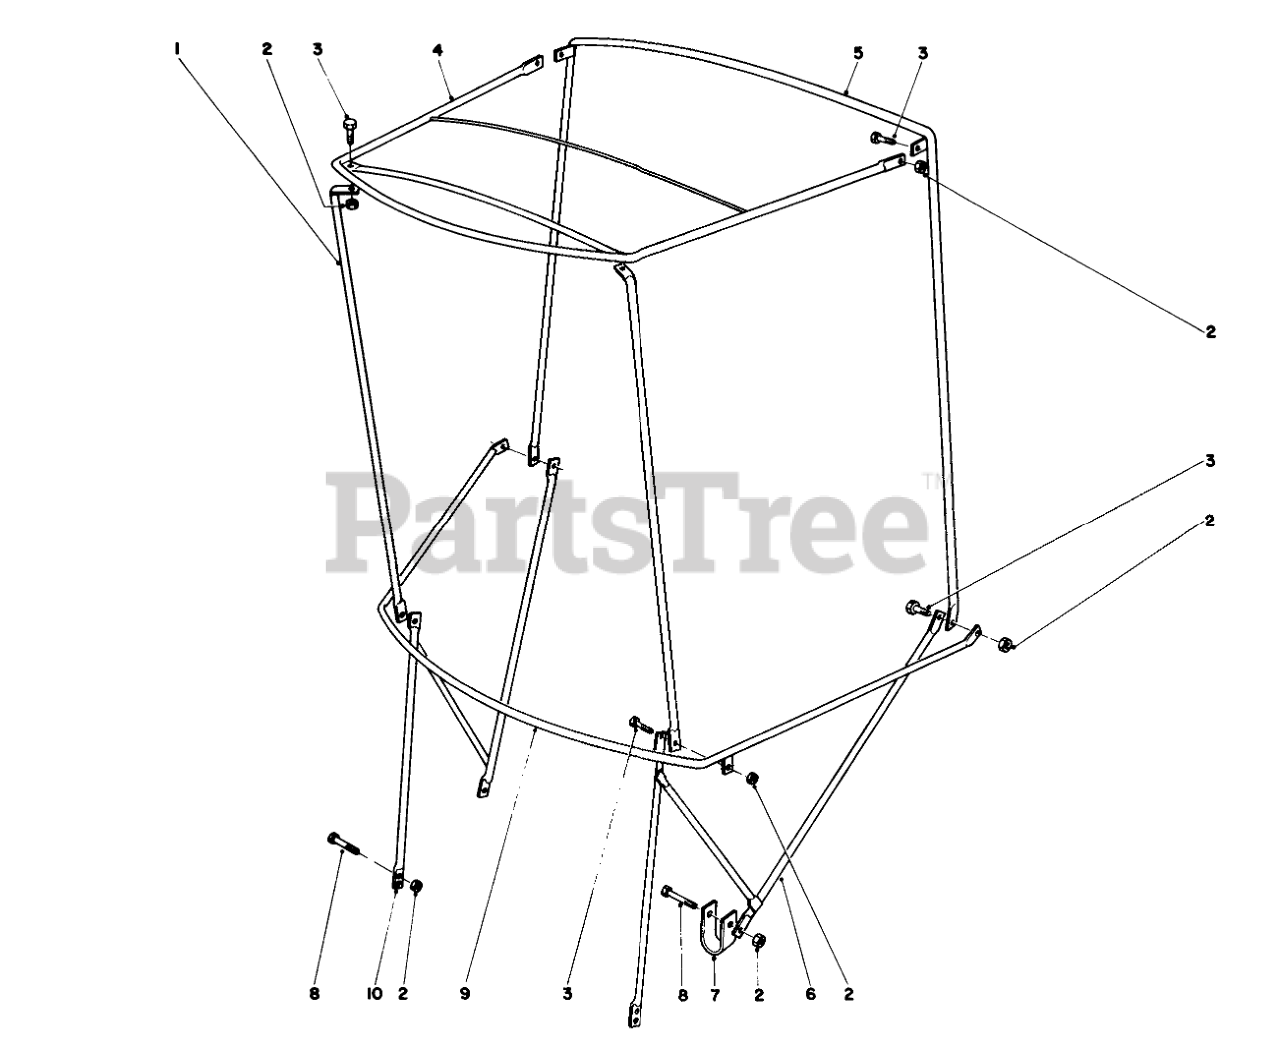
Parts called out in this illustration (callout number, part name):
2	NUT-HEX, SIDE DEFORM
3	SCREW-HH
4	FRAME-TOP
5	BOW-VERTICAL, REAR
6	ATTACHING BRKT L
7	U CLAMP
8	SCREW-HH
9	BOW-CURVED
10	ATTACHING BRKT R
